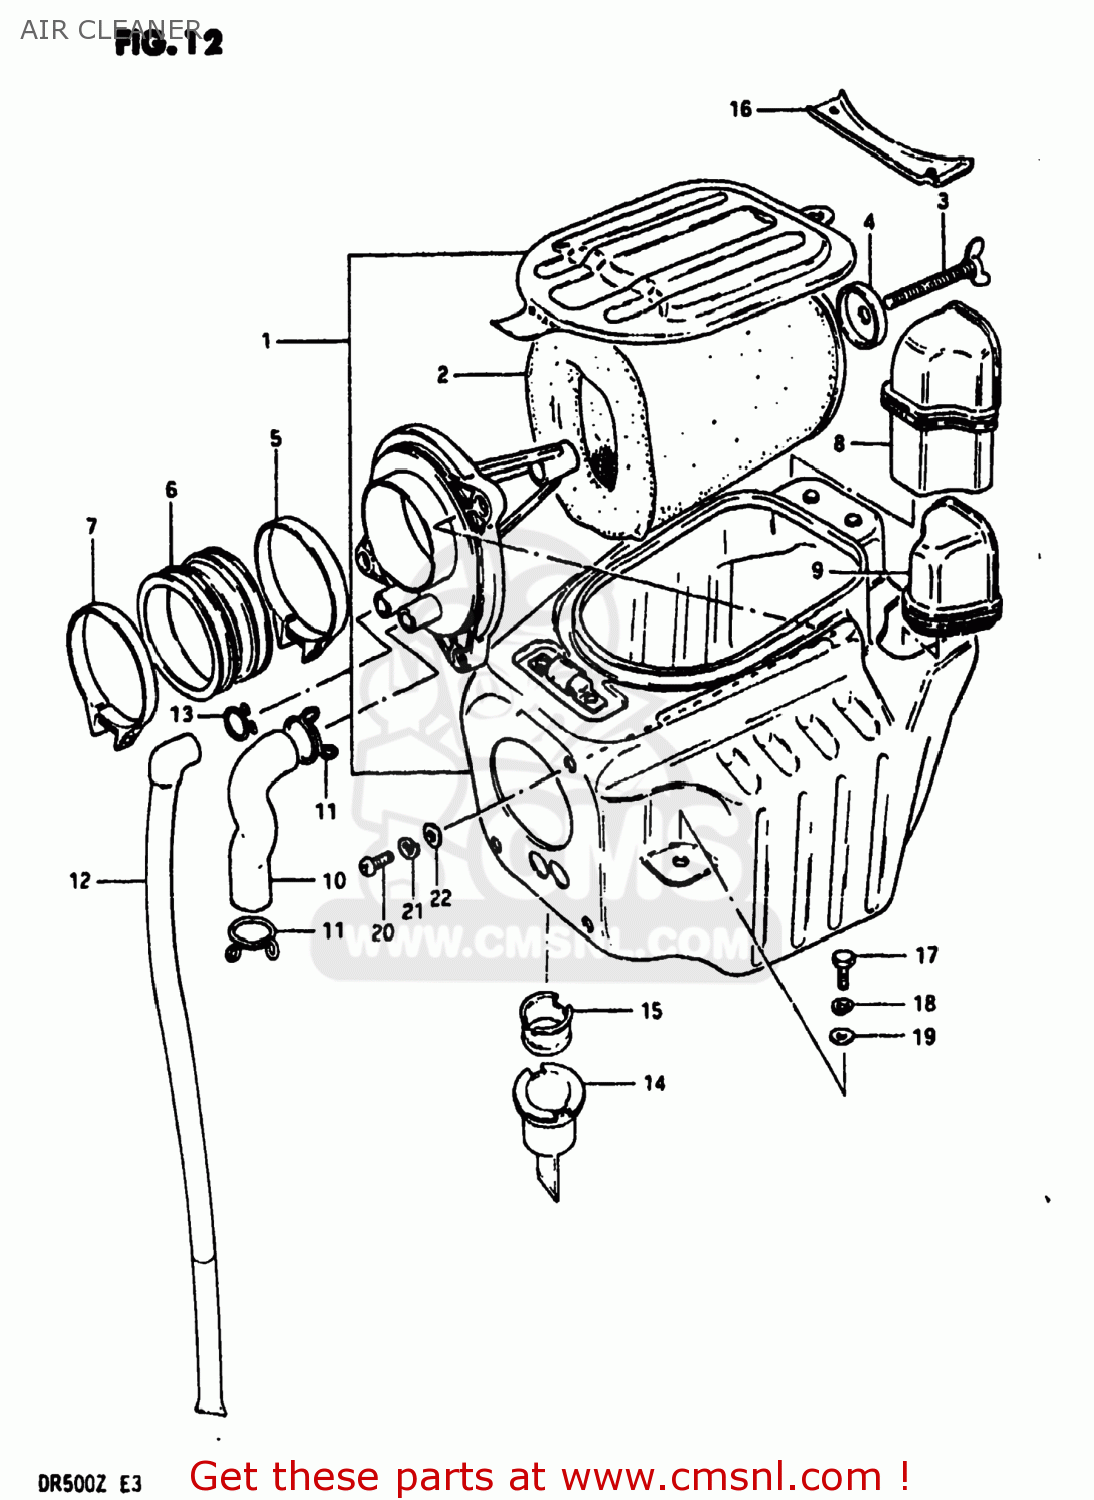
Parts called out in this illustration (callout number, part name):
1	CLEANER ASSEMBLY,AIR
2	FILTER
3	WING BOLT,AIR CLEANER
4	HOLDER,FILTER
5	CLAMP
6	TUBE,OUTLET
7	CLAMP
8	TUBE,INLET
9	HOSE,INLET
10	TUBE,BREATHER
11	CLIP
12	DRAIN TUBE
13	CLIP
14	HOSE,AIR CLEANER DRAIN
15	STOPPER,DRAIN
16	BRACKET,AIR CLEANER
17	BOLT, UPPER
18	LOCK WASHER
19	WASHER
20	SCREW 6X12
21	LOCK WASHER
22	WASHER
